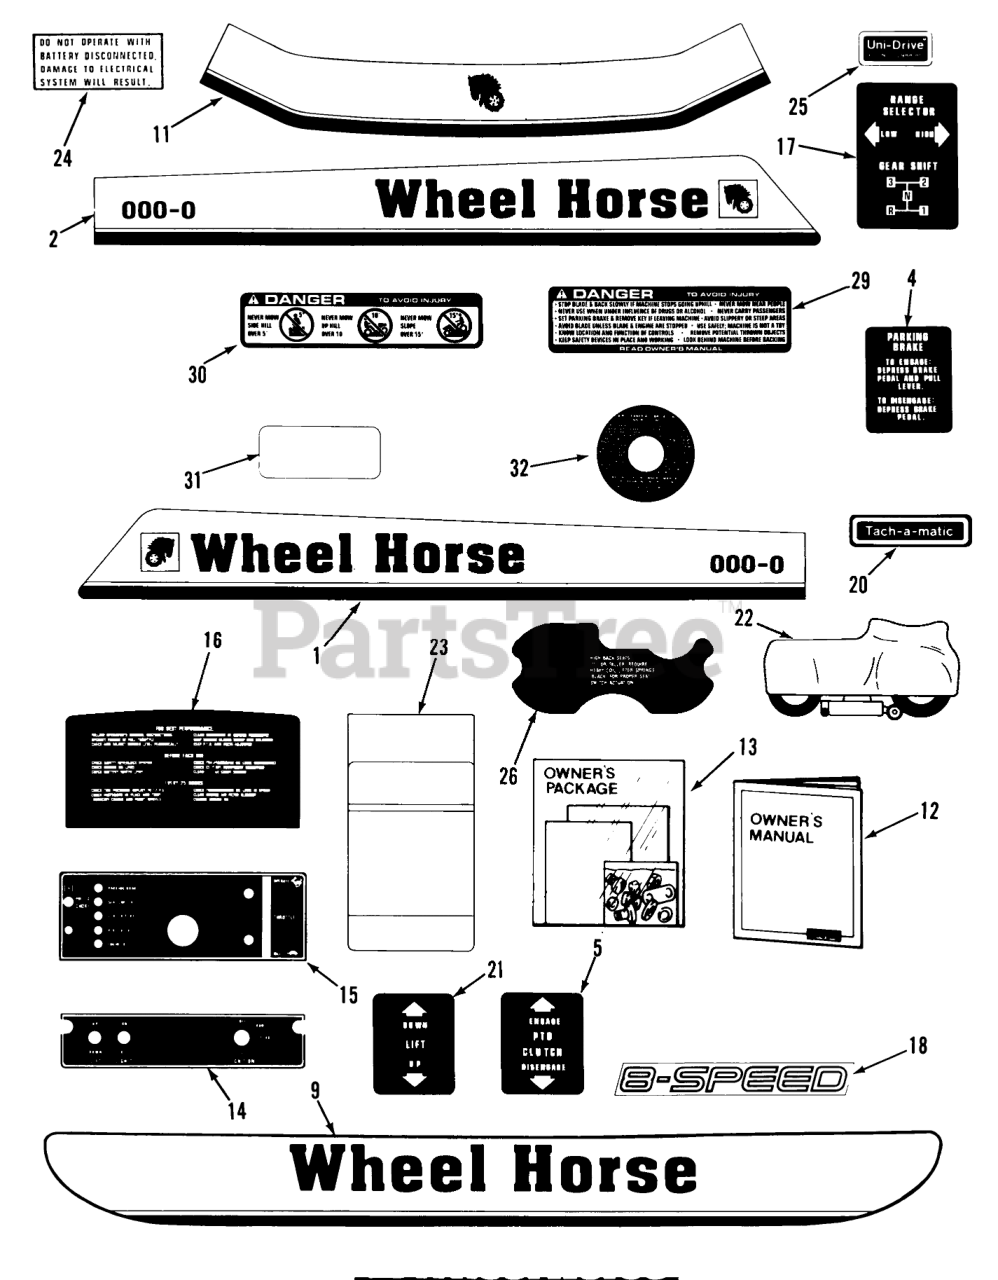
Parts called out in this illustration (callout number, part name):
1	DECAL HOOD RH
2	DECAL HOOD LH
4	DECAL-PARKING, BRAKE
5	DECAL PTO CLUTCH
9	Decal-Rear Fender
11	Decal-Hood Front
12	Owners Manual-Tractor
13	Loose Parts Package 308
14	DECAL BACK PLATE
15	DECAL LOWER DASH
16	Decal-Rear Hood
17	DECAL-SHIFT PATTERN
18	DECAL 8SPD
19	DECAL AUTOMATIC
20	DECAL-TACHAMATIC
21	DECAL-LIFT
22	Vinyl Tractor Cover
23	Decal-Maintenance
24	DECAL ELECT SYSTEM
25	Decal-Unidrive
26	DECAL-SEAT LIFTER
29	Decal-Danger
30	Decal-Danger
31	DECAL-OVERLAY
32	Decal-Air Cleaner
